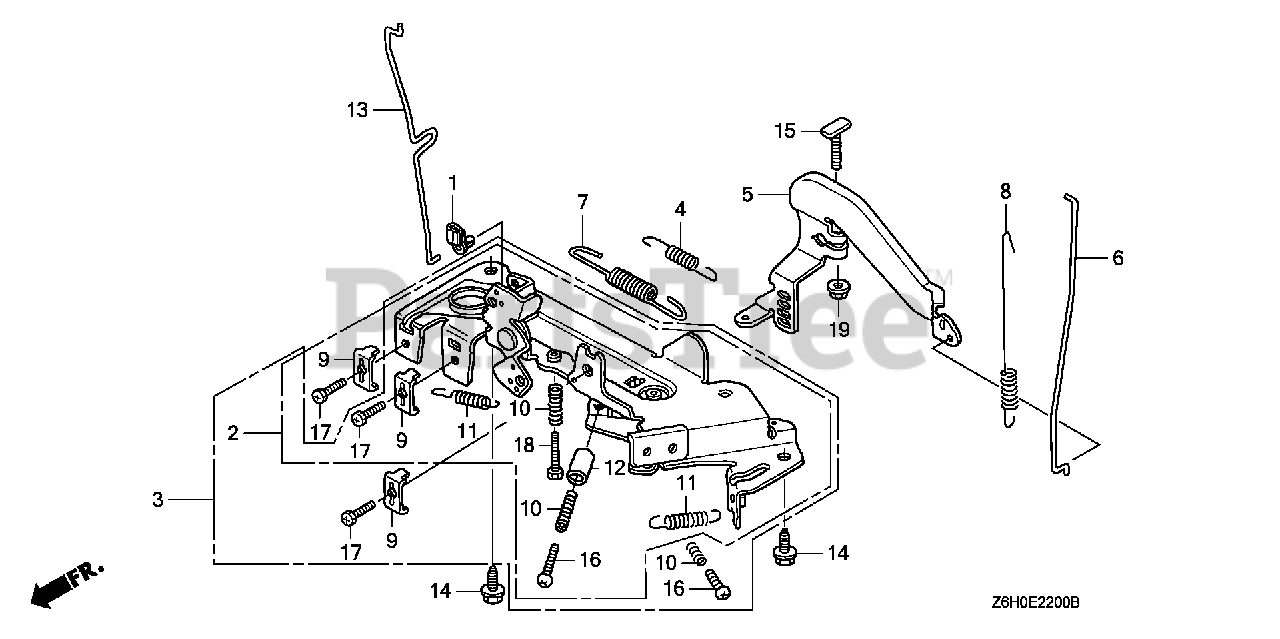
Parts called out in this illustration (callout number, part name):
1	JOINT, ROD
2	CONTROL ASSY.
4	SPRING, STARTER
5	ARM, GOVERNOR
6	ROD, GOVERNOR
7	SPRING, GOVERNOR
8	SPRING, THROTTLE RETURN
9	HOLDER, CABLE
10	SPRING, CONTROL ADJUSTING
11	SPRING, CABLE RETURN
12	COLLAR, STOPPER
13	ROD, CHOKE CONTROL
14	BOLT, FLANGE (6X14) (CT200)
15	BOLT, GOVERNOR ARM
16	SCREW, RECESSED (5X28) (BLACK)
17	BOLT, RECESSED (5X16)
18	BOLT, RECESSED (5X25)
19	NUT, FLANGE (6MM)
